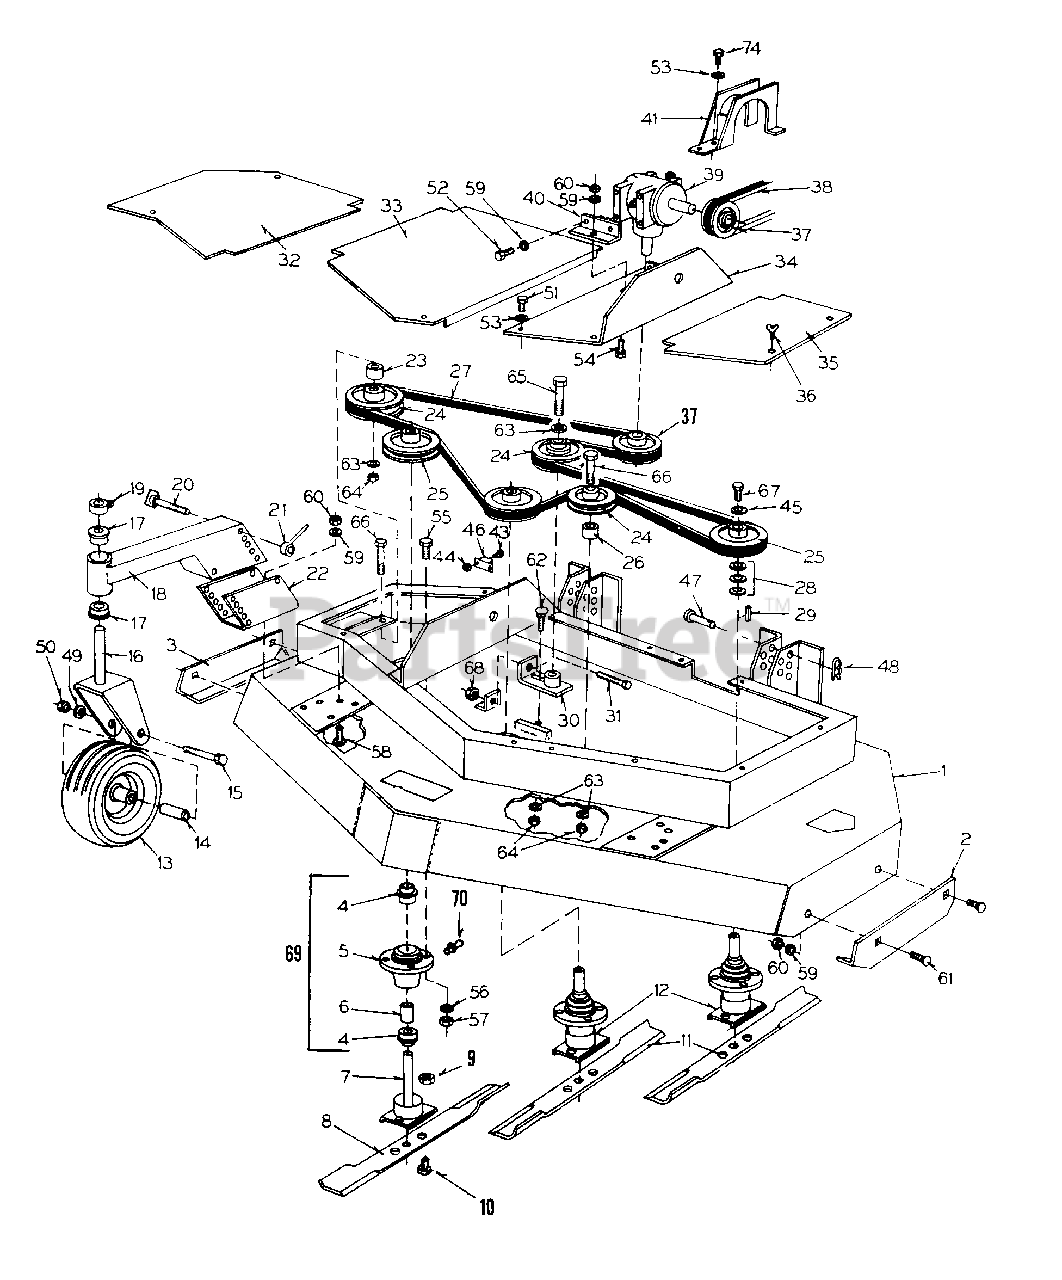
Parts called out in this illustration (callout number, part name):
1	DECK - rear discharge 52"
2	SHOE - skid L.H.
3	SHOE - skid R.H.
4	BEARING - spindle 7/8"
5	HOUSING - spindle
6	SPACER - spindle
7	SHAFT - spindle L.H. rotation
8	BLADE - L.H. rotation
9	NUT - 3/8" - 16 lock
10	BOLT - 3/8" - 16 x 1
11	BLADE - R.H. rotation
12	SHAFT - spindle
14	AXLE - gauge wheel
15	BOLT - 1/2" - 13 x 6-1/2"
16	FORK - gauge wheel
18	MOUNT - gauge wheel
19	COLLAR - set 1"
20	BOLT - wing 3/8" - 16 x 4-1/2"
21	NUT - gauge wheel handle 3/8" - 16
22	BRACKET - gauge wheel mount
23	SPACER - idler pulley
24	PULLEY - idler 5"
25	PULLEY - spindle 4-1/2"
26	SPACER - idler pulley
28	WASHER - spacer
29	KEY - 3/16" x 3/16" x 1"
30	TIGHTENER - belt
31	BOLT - 1/4" - 20 x 4"
33	COVER - center
34	MOUNT - gear box
36	SCREW - thumb 1/4" - 20 x 1/2"
37	PULLEY - gear box input
38	BELT - drive (1800C)
39	GEAR BOX - angle drive
40	ANGLE - gear box mount
43	SCREW - #10 - 32 x 1/2"
44	NUT - lock #10 - 32
45	WASHER - spindle
46	BREAKER - circuit 10 amp
47	PIN - clevis 1/2" x 1-1/2"
48	PIN - cotter, hair
49	LOCKWASHER - 1/2"
50	NUT - 1/2" - 13
51	BOLT - 1 /4" - 20 x 34"
52	BOLT - 5/16" - 18 x 1"
53	LOCKWASHER - 1/4"
54	BOLT - 5/16" - 18 x 3/4"
55	BOLT - 7/16" - 14 x 1-1/4"
56	LOCKWASHER - 7/16"
57	NUT - 7/16" - 14
58	BOLT - carriage 5/16" - 18 x 1"
59	LOCKWASHER - 5/16"
60	NUT - 5/16"
61	BOLT - carriage 5/16" - 18 x 3/4"
62	BOLT - carriage 3/8" - 16 x 1"
63	LOCKWASHER - 3/8"
64	NUT - 3/8" - 16
65	BOLT - 3/8" - 16 x 1-1/4"
66	BOLT - 3/8" - 16 x 2-1/2
67	BOLT - 3/8" - 24 x 1-1/4"
68	NUT - lock 1/4" - 20
69	HOUSING ASSEMBLY - spindle
70	FITTING - grease 1/4" - 28
